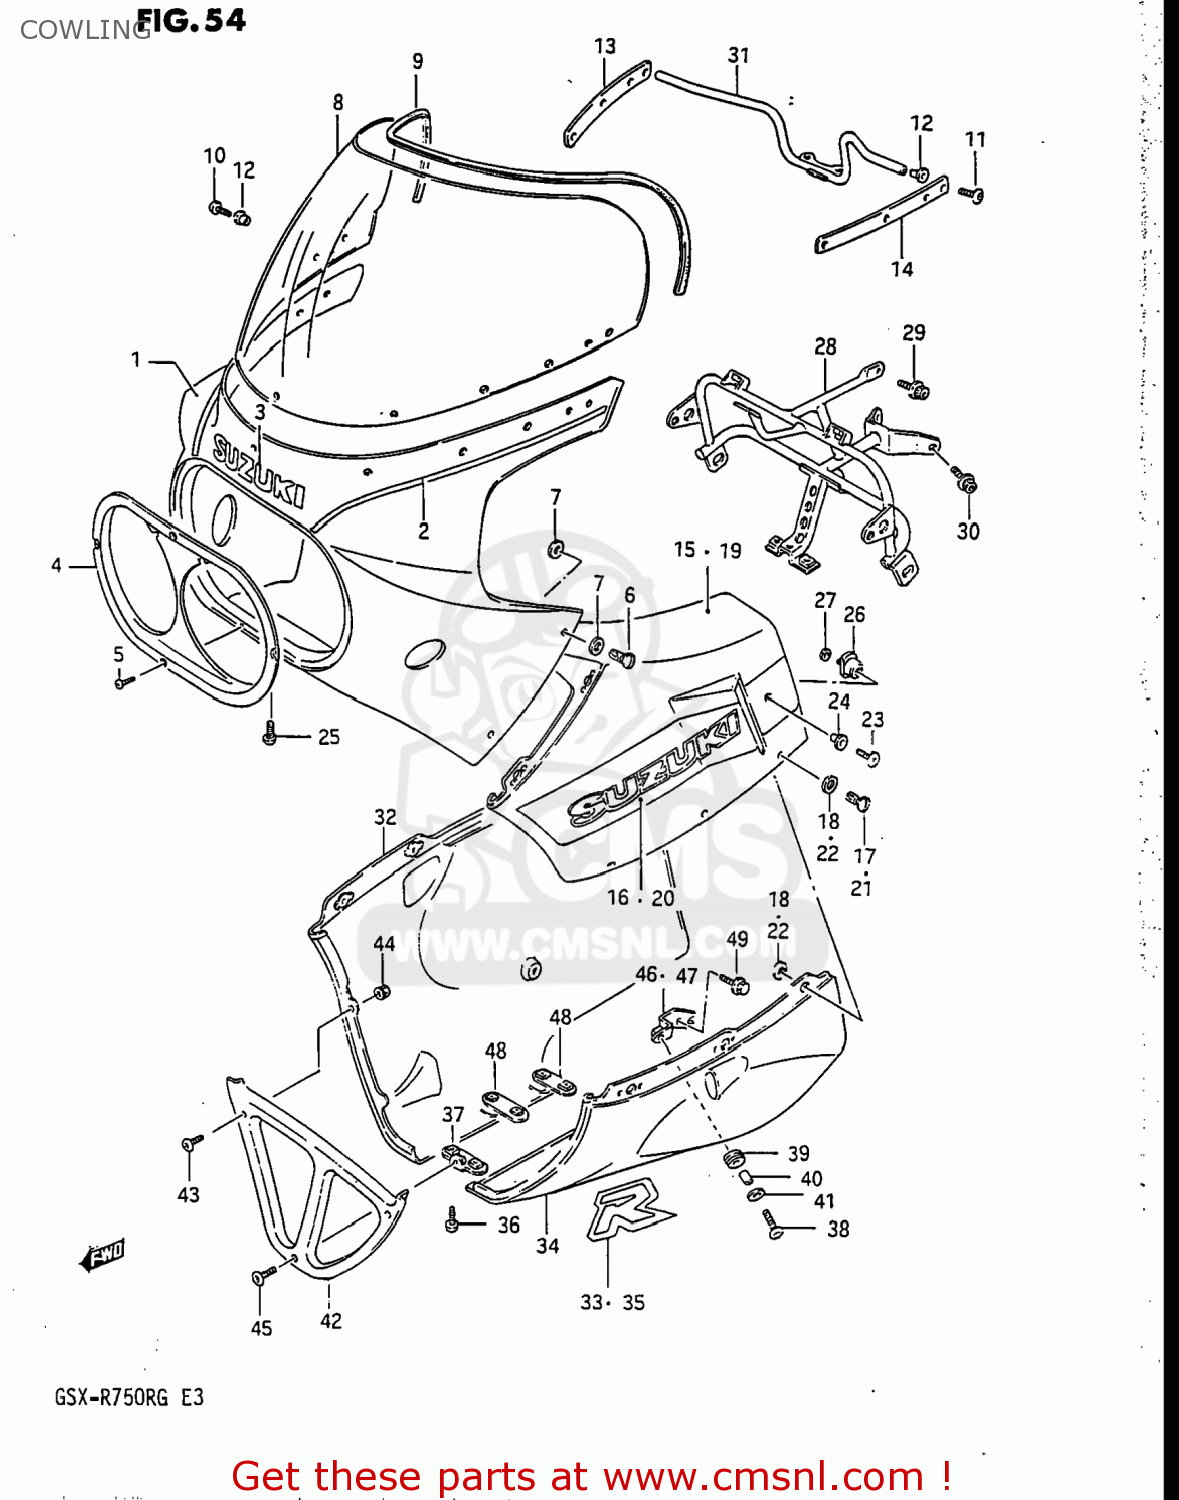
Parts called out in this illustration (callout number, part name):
1	BODY ASSEMBLY,COWLING SUB
2	TAPE SET,BODY COWLING STRIPE
3	EMBLEM,COVER SEAT TAIL
4	COVER,COWLING FR
5	SCREW
6	FASTENER
7	WASHER,FASTENER
8	WINDSCREEN
9	MOLDING,SCREEN
10	SCREW(5X14)
11	SCREW(5X18)
12	NUT,COWLING SCREEN
13	PLATE,RR VIEW MIRROR,R
14	PLATE,RR VIEW MIRROR,L
15	COVER ASSEMBLY,COWLING
16	TAPE SET,SIDE COWLING,S,RIGHT
17	FASTENER
18	WASHER,FASTENER
19	COVER,COWLING SIDE,LEFT
20	TAPE SET,SIDE COWLING,S,LEFT
21	FASTENER
22	WASHER,FASTENER
23	SCREW(6X12)
24	WASHER
25	SCREW(6X16)
26	CUSHION,COWLING
27	WASHER,LOCK
28	BRACE,COWLING FR
29	BOLT
30	BOLT
31	BRACE,COWLING BODY RR
32	COVER,COWLING,LOWER,RIGHT
33	EMBLEM,COWLING,LOWER
34	COVER,COWLING,LOWER,LEFT
35	EMBLEM,COWLING,LOWER
36	SCREW(6X16)
37	BRACE,COWLING LWR COVER
38	SCREW(6X20)
39	CUSHION
40	SPACER
41	WASHER(6.5X18X1)
42	COVER,COWLING,LOWER,FRONT
43	SCREW(5X14)
44	NUT
45	SCREW(6X16)
46	BRACE,COWLING LWR,R
47	BRACE,COWLING LWR,L
48	BRACE,COWLING LWR COVER RR
49	BOLT
